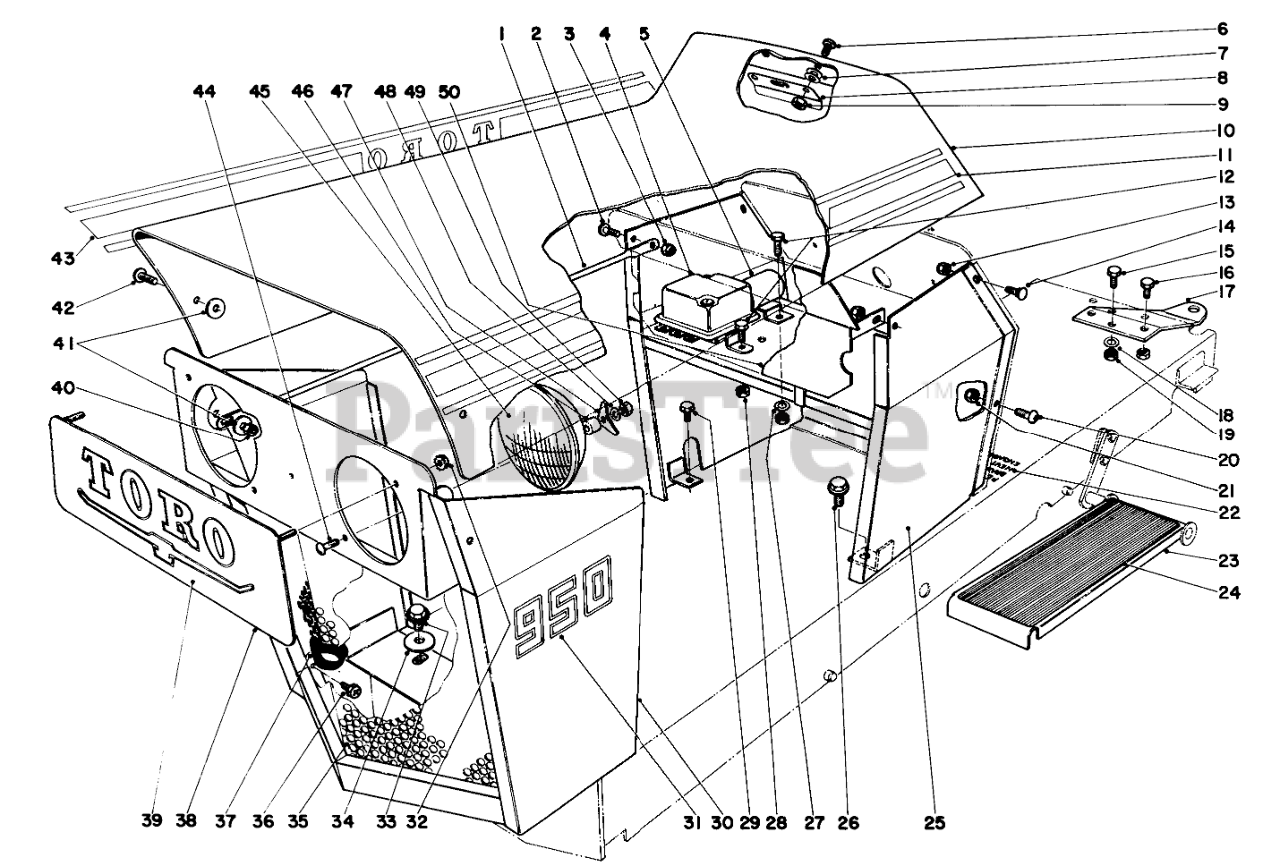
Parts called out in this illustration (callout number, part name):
1	Rod Hood Support
2	Capscrew Socket Head
4	Voltage Regulator
5	Solenoid
6	Screw, Phillips
7	Washer
8	Hood Latch
11	Decal Side L.H.
12	SCREW-HH
14	SCREW-CARR
15	SCREW-HH
16	SCREW-HH
17	Chassis Hitch
18	WASHER-FLAT
20	Capscrew Socket Head
21	Nut
22	Decal Clutch Release
23	Foot Rest
24	Pad Foot Rest
25	Battery Support
26	Sems Screw
27	WASHER-FLAT
29	Screw-HH
30	Grille Frame W.A.
31	Decal Side Grille 950
33	Sems Screw
34	Washer
35	Grille
36	Self Tapping Screw
37	Grommet
38	Head Light Cover
39	Decal Cover Plate
40	Nut
41	Washer
42	Capscrew Socket Head
43	Side Hood R.H.
44	SCREW-SRH
45	HEAD LAMP
46	Spacer
47	Clip 960
48	WASHER-LOCK/SP
49	NUT-HEX
50	Heat Deflector
